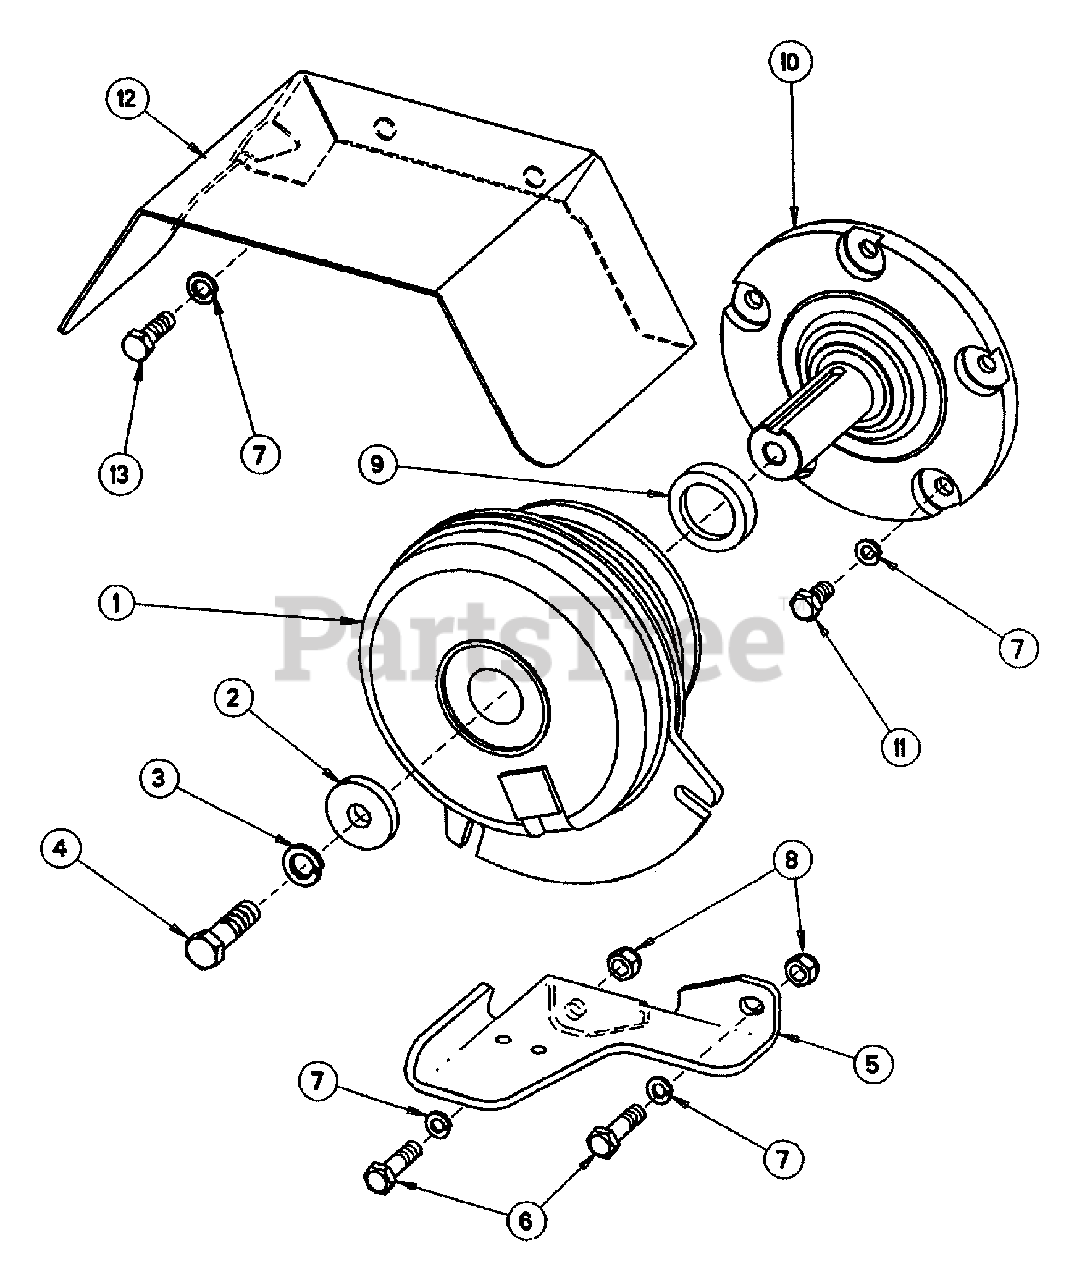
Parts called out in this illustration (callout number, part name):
1	ELECTRIC CLUTCH
2	SPACER, Clutch
3	WASHER, 7/16 Split Lock
4	SCREW, 7/16-20 x 1-1/2" Hex Head Cap, Grade 5
5	BRACKET, Clutch Torque
6	SCREW, M8-1.25 x 30 Hex Head Cap
7	WASHER, .32 Split Lock
8	NUT, M8-1.25 Hex Nyloc
9	SPACER, Clutch
10	SHAFT, PTO
11	SCREW, M8-1.25 x 16mm Hex Head Cap
12	BRACKET, Clutch Guard
13	BOLT, M8-1.25 X 25MM GD8.8
